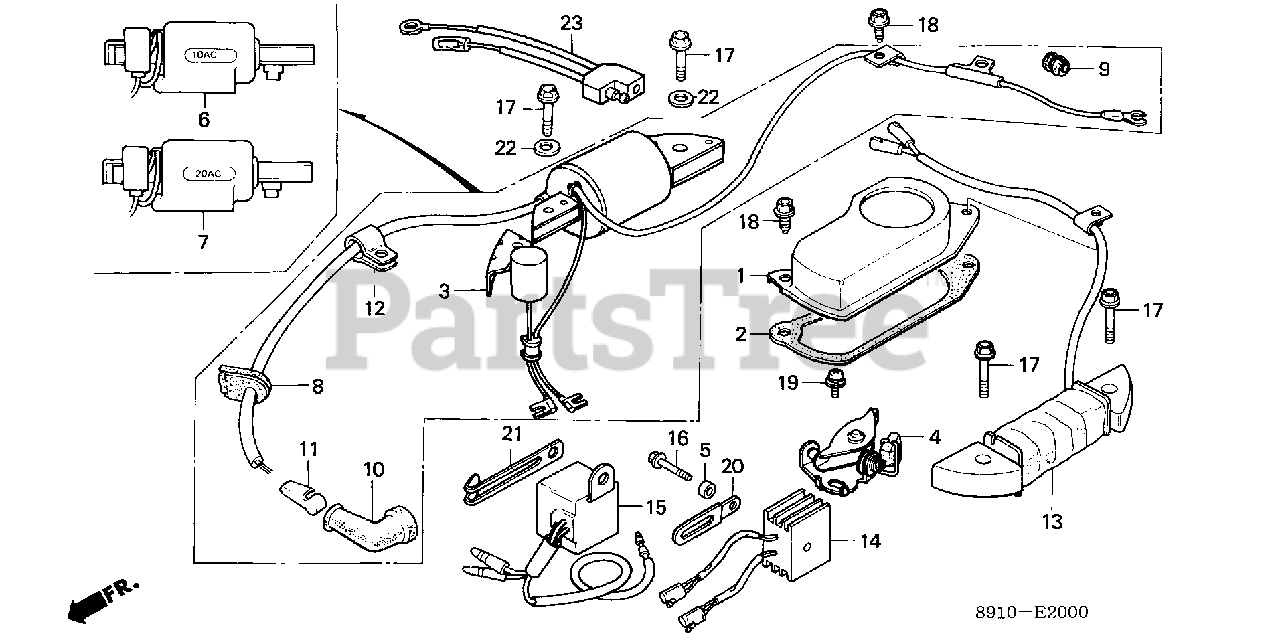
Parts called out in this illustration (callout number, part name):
1	COVER, BREAKER
2	GASKET, COVER
4	POINTS ASSY.
6	COIL ASSY., IGNITION
8	GROMMET, WIRE
9	GROMMET, PRIMARY WIRE
10	CAP, IGNITION (TOYO)
11	TERMINAL, PLUG
12	CLAMP, IGNITION WIRE
17	BOLT, FLANGE (6X32)
18	BOLT, FLANGE (5X14)
19	SCREW-WASHER (5X12)
22	WASHER, PLAIN (6MM)
